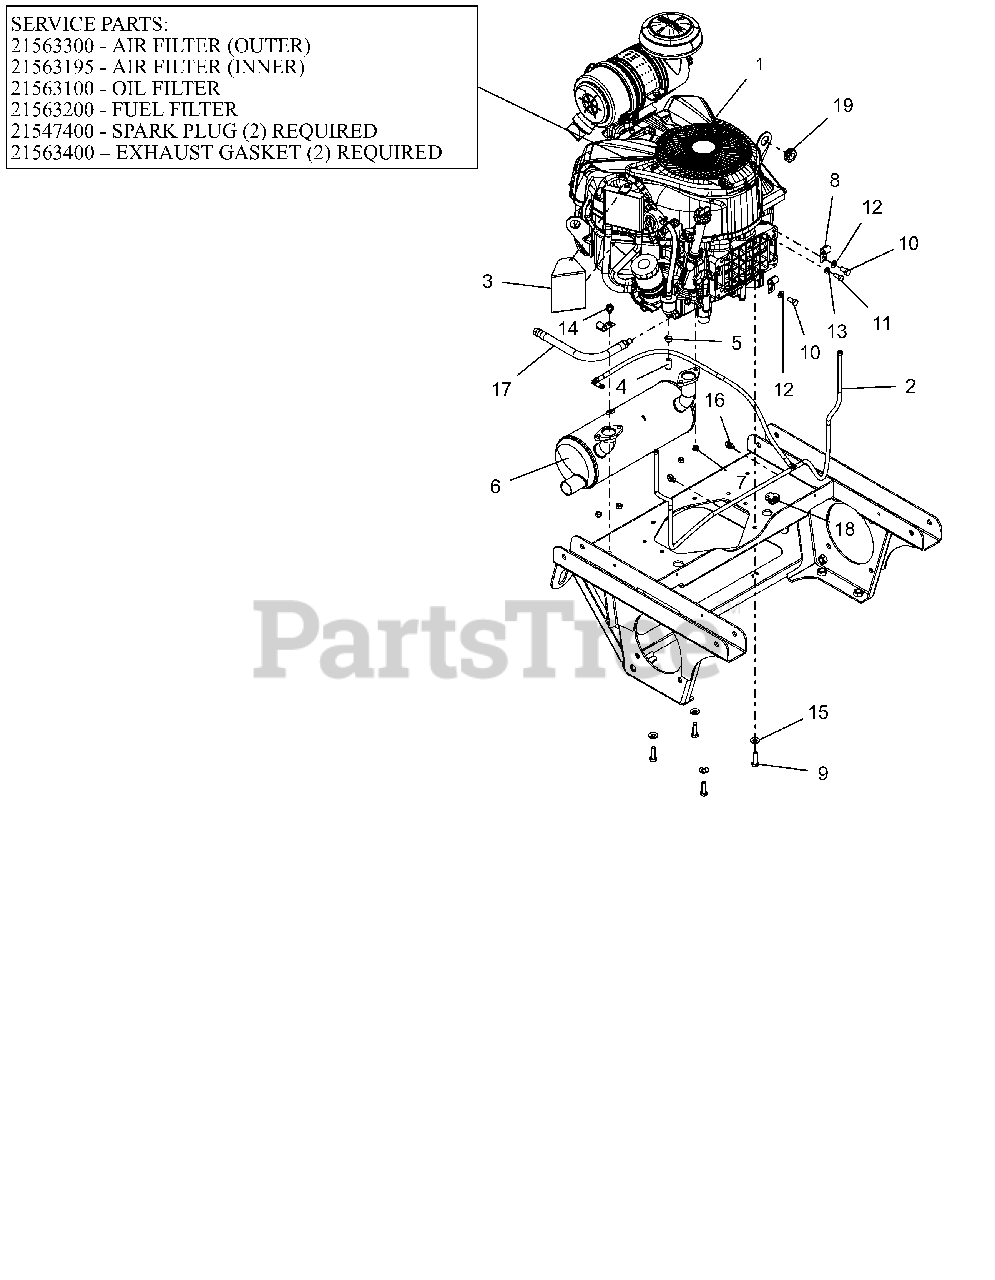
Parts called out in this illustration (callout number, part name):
1	ENGINE, YAMAHA MX 825V
1	AIR FILTER (OUTER) - YAMAHA
1	AIR FILTER (INNER) - YAMAHA
1	FILTER, OIL - YAMAHA 824
1	FILTER-FUEL YAMAHA 824
1	PLUG, SPARK
1	GASKET, MUFFLER YAMAHA 824
2	ASM, VAPOR LINE
3	DEFLECTOR,YAMAH OIL COOLER AIR
4	HOSE, .25 LOW-PERM BULK GAS
5	CLAMP, FUEL LINE
6	MUFFLER, YAMAHA
7	NUT-LK-TOP M8-1.25 YWZC
9	BLT-HEX.38-16X1.25 G5YZ NYTORQ
10	@BLT-HEX .38-16X.75 GR5 YWZC
11	@BLT-HEX .31-18X.75 GR5 YWZC
12	@WSHR-LK .38X.094 REG YWZC
13	@WSHR-LK .31X.078 REG YWZC
14	@SCR-TAP .38-16X.50 HWH TR YWZ
15	WASHER, 3/8" SPRING DISC
16	ROUTING CLIP (1/2" ID)
17	HOSE, OIL DRAIN
18	HARNESS, YAMAHA CARB ADAPTER
19	GROMMET,RUBBER.688 IDX1.000 OD
